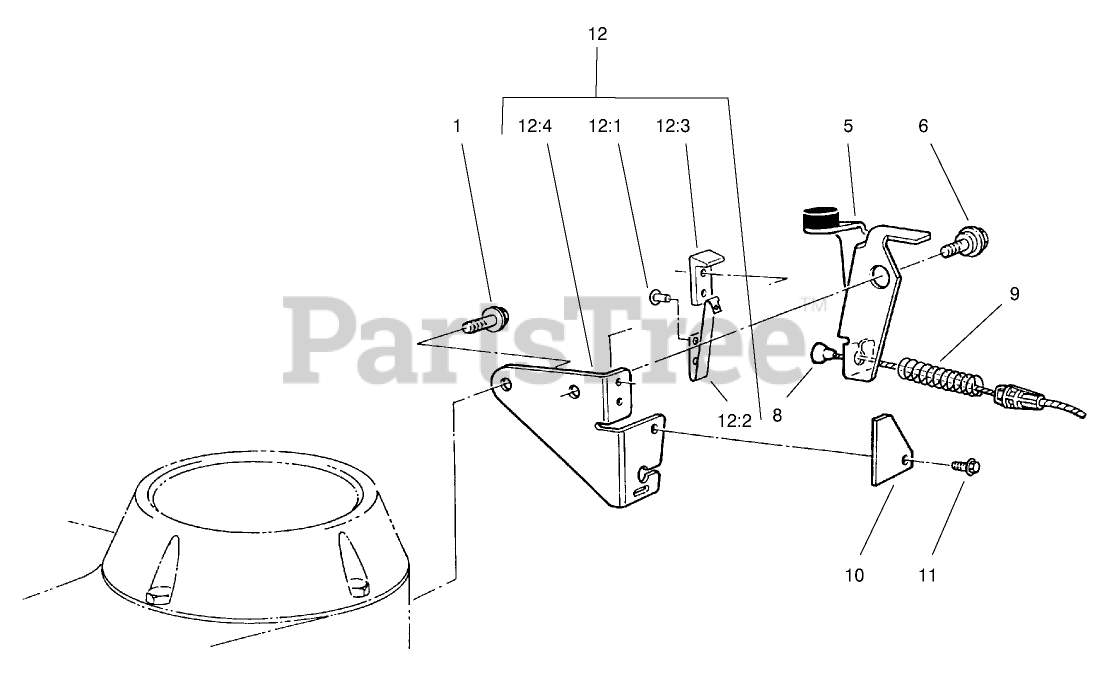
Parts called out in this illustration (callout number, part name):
1	SCREW-HWH
5	BRAKE PLATE ASM
6	SCREW-SHOULDER
8	BRAKE CABLE
9	SPRING-COMPRESSION
10	STOP-GROUND STRAP
11	SCREW-HWH
12	MTG PLATE ASM
12:1	RIVET-PLASTIC
12:2	STRAP-GROUND
12:3	STRAP-INSULATING
12:4	PLATE-BRAKE
